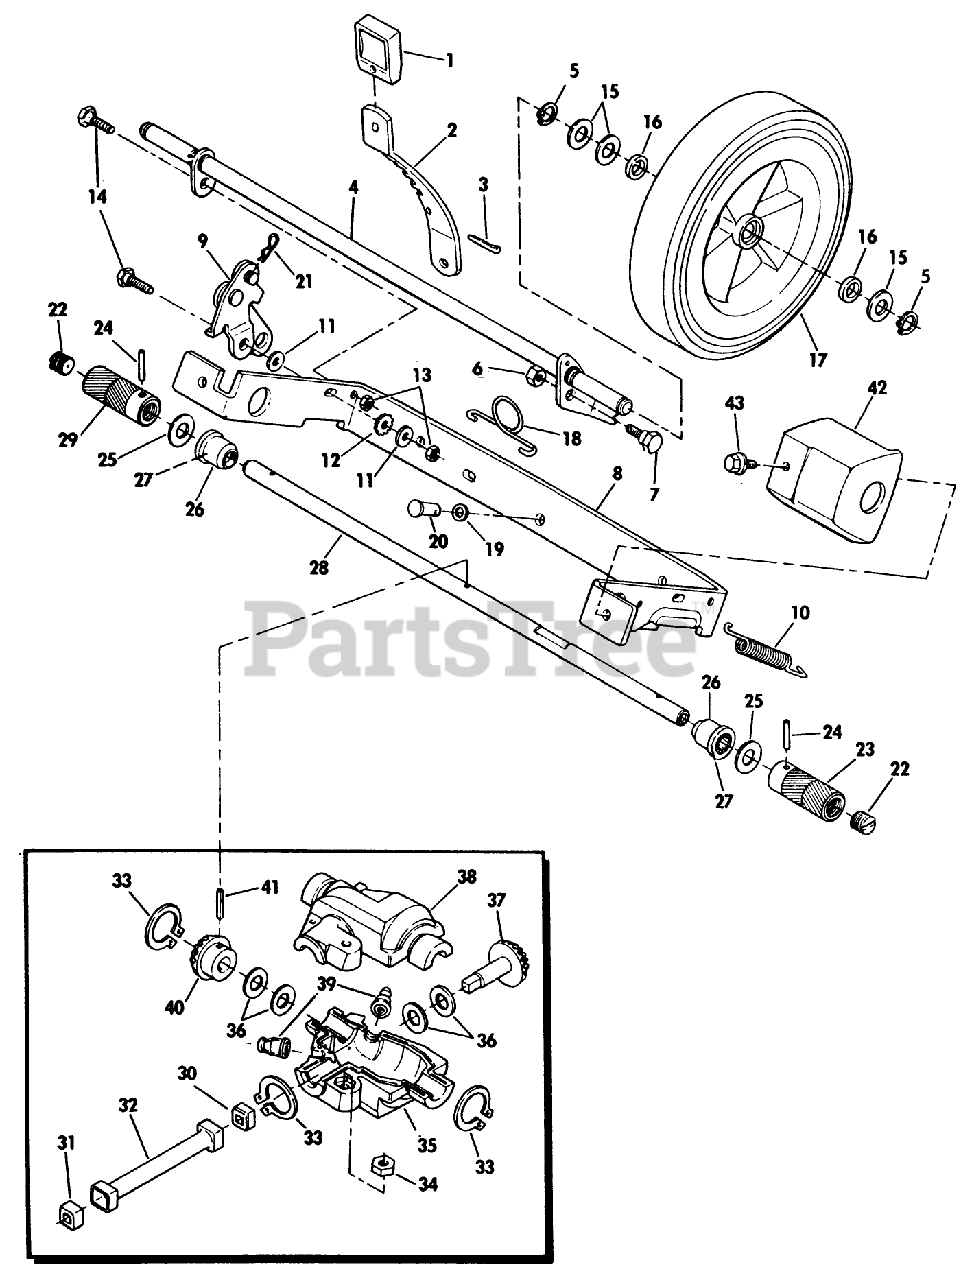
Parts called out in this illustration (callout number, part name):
5	RET RING
6	LOCKNUT E
7	BOLT RB&W
8	BRK-21" AXLE
11	WASHER S
13	STOP NUT
14	BOLT RB&W
15	SPACER
18	SPRING N.A.S
19	WASHER SPRING LAR
22	GREASE PLUG
27	BEARING AY F
30	BUSHING
31	BUSHING
34	LOCKNUT E
36	THRUST WASHER
39	ZERK FITTING
41	ROLL PIN
